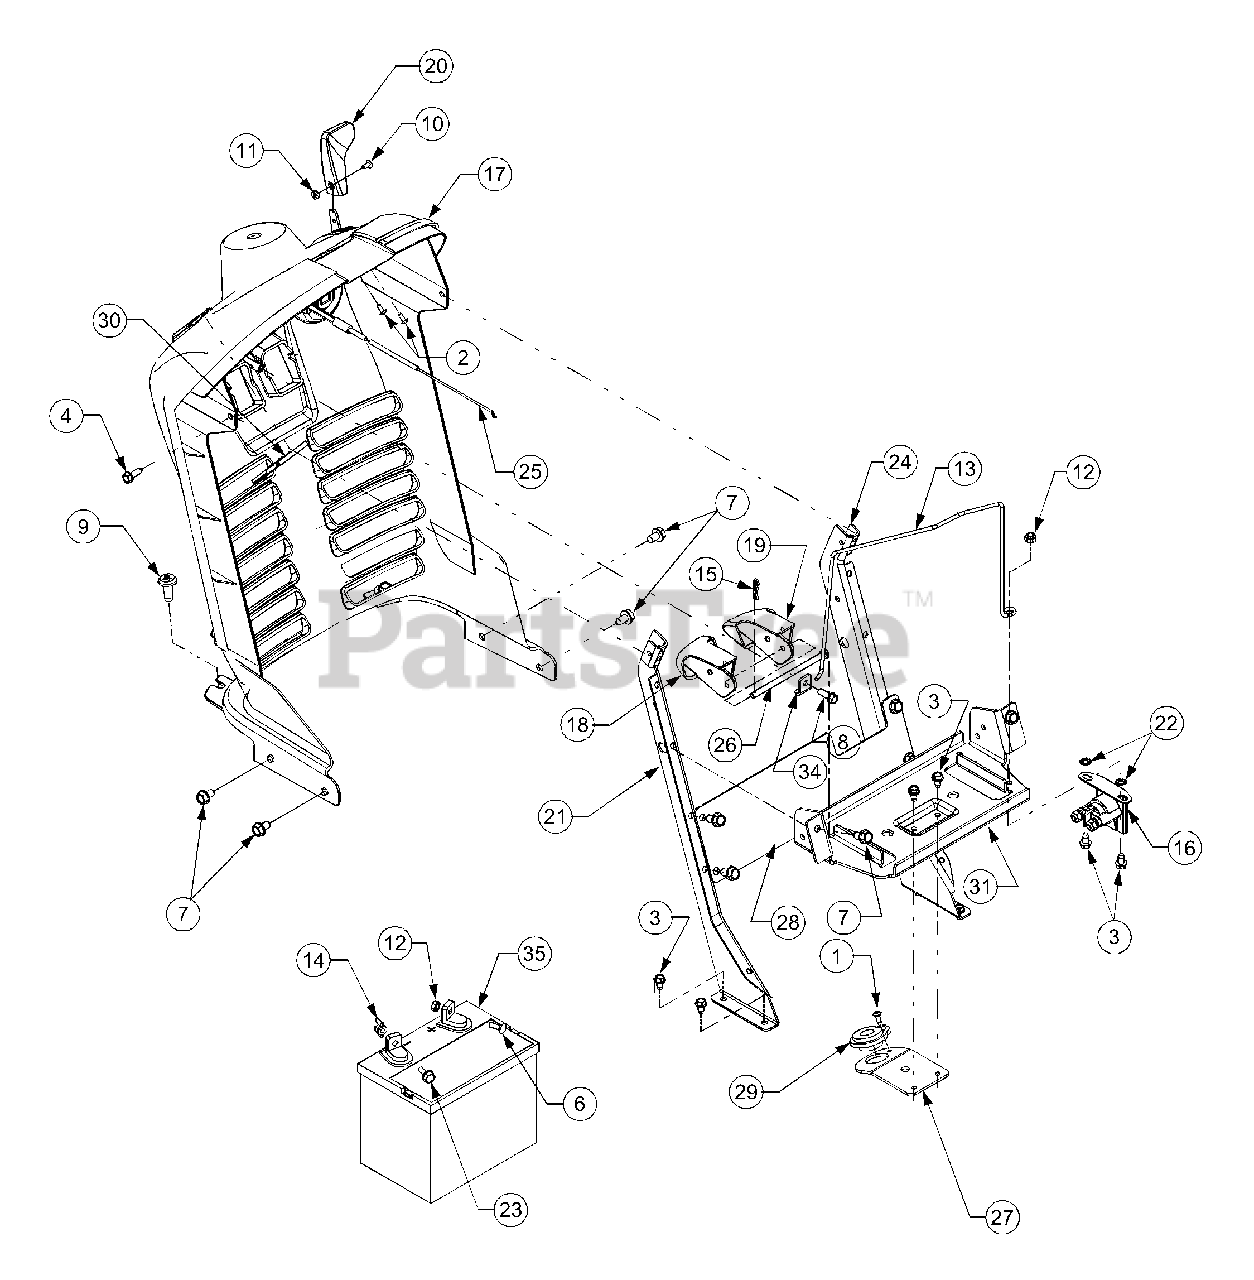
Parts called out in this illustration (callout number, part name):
1	Screw, #10-16 x .625
2	Screw, #10-24 x .375
3	Screw, Self-tapping, 1/4-20, 0.500
4	Screw, Hx. Wash. Hd, Tapp. 1/4-20 x .75
5	Screw, Hx. Wash. Hd, Tapp, 5/16-18, .875
6	Screw, Carriage, 1/4-20, .75,
7	Screw, Hx. Wash. Hd, Tapp, 5/16-12 x .75
8	Screw, 1/4-15, 0.750
9	Screw, Torx Hd. Tapp. 5/16-18 x .75
10	Screw, Machine, #8-32, 0.375, Trus Phillips
11	Nut, 8-32
12	Nut, Nylon Lock, 1/4-20
14	Nut, Wing, 1/4-20
15	Internal Cotter Pin, .072 x 1.13
16	Solenoid, 12V, 100 Amp
17	Dash
18	Lever, Dash, Cruise
19	Lever, Dash, Brake
20	Knob, Throttle Control
23	Screw, Shoulder, 1/4-20, .25 x .15
25	Control, Choke, 40.5
26	Rod, .250 Dia x 4.25 Lg.
30	Bracket, PTO Switch Retainer
35	Battery, 270 CCA
